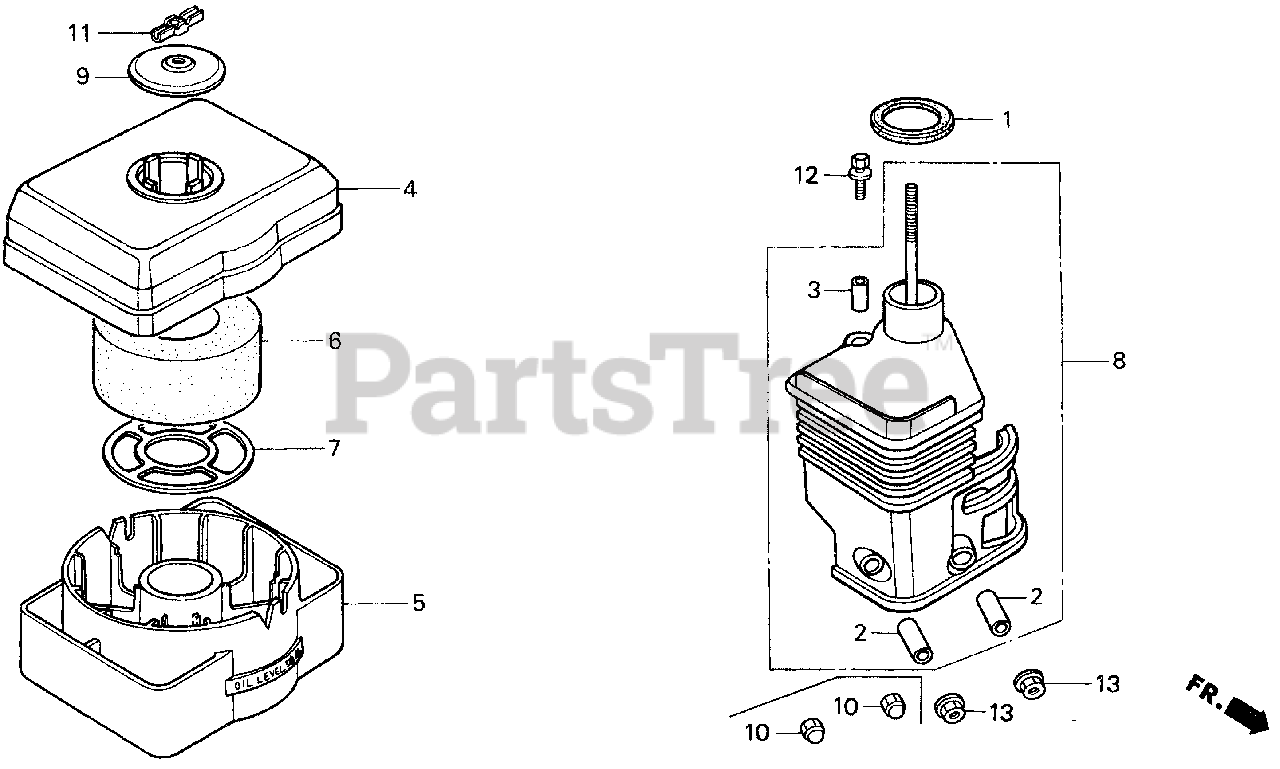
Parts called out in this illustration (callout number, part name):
1	GASKET, ELBOW
2	COLLAR, AIR CLEANER
3	COLLAR B, AIR CLEANER
4	BODY, CLEANER (OIL BATH)
5	PAN, CLEANER OIL (OIL BATH)
6	ELEMENT, AIR CLEANER (OIL BATH)
7	GRID, AIR CLEANER
8	ELBOW, AIR CLEANER
9	CAP, CLEANER
10	NUT, CAP (6MM)
11	WINGNUT (6MM)
12	BOLT-WASHER (6X20)
12	BOLT, FLANGE (6X20)
13	NUT, FLANGE (6MM)
